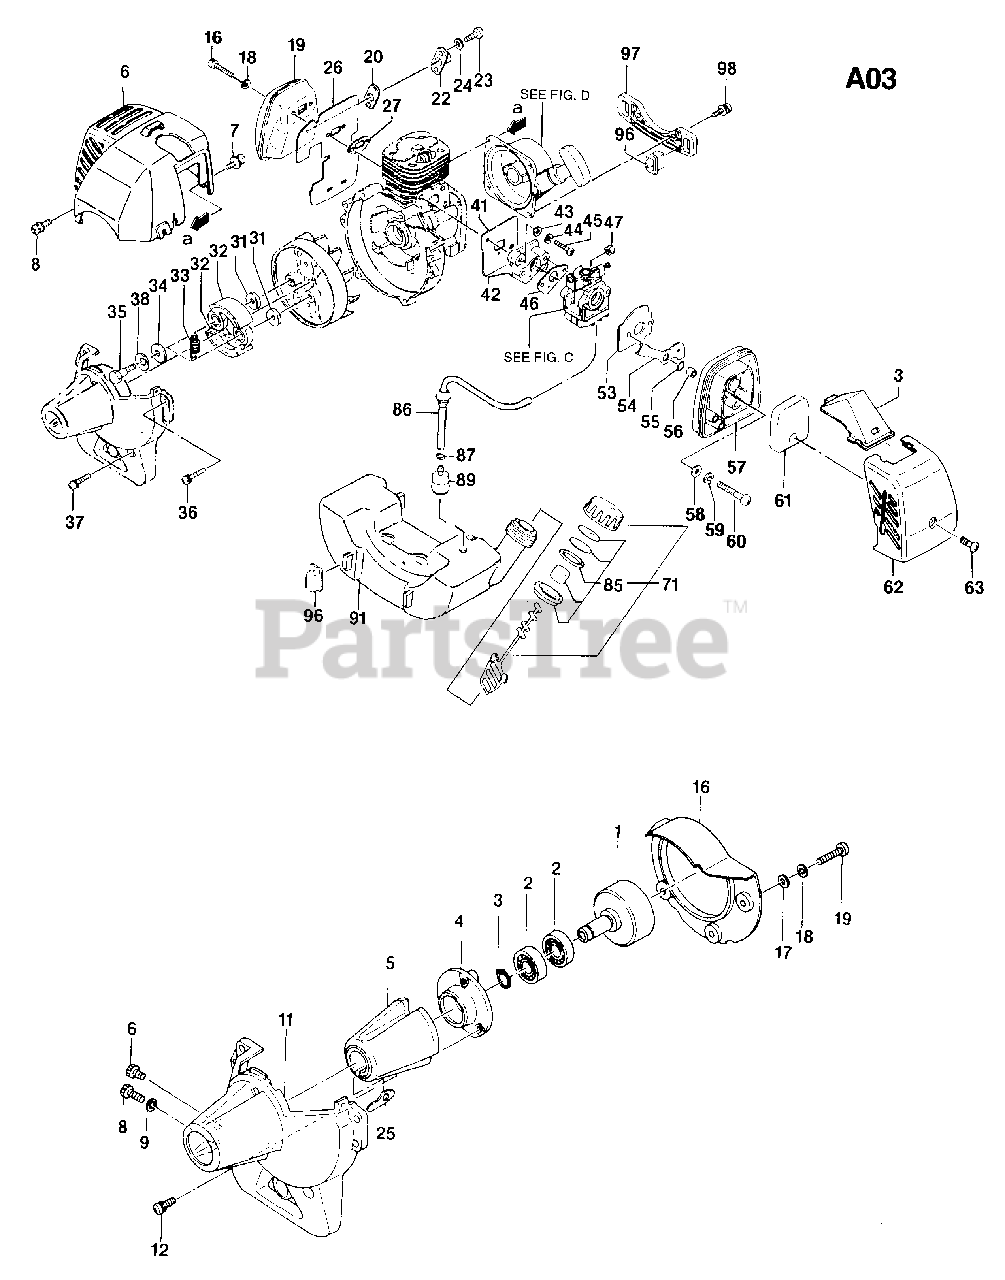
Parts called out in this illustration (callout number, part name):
16	SCREW MC6S 5X50
18	WASHER 5.3X12
23	SCREW MC6S 4X8
24	SPRING WASHER 4.1X7.1
43	WASHER
44	SPRING WASHER
58	WASHER
59	SPRING WASHER
